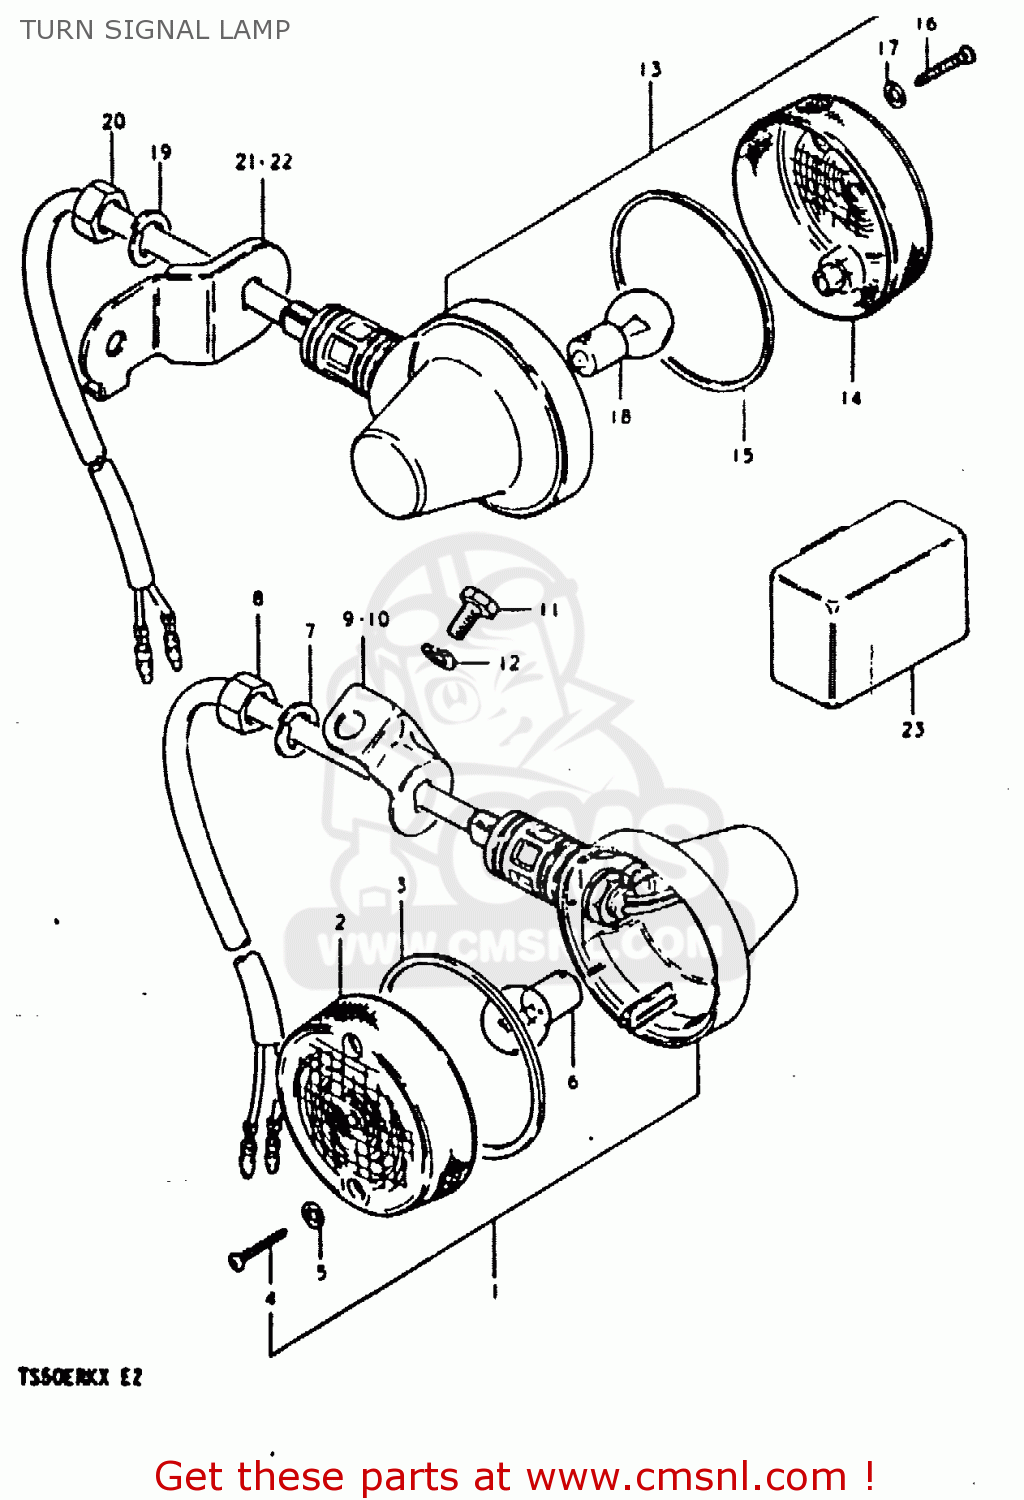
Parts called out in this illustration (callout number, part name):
1	LAMP ASSY,RR TURNSIGNAL
2	LENS
3	GASKET (NAS)
4	SCREW TAPP.
5	GASKET (NAS)
6	BULB (6V,18W)
7	WASHER,LOCK 12
8	NUT
9	BRACKET,TURNSIGNAL LAMP,R
10	BRACKET,TURNSIGNAL LAMP,L
11	BOLT
12	LOCK WASHER
13	LAMP ASSY,RR TURNSIGNAL
14	LENS
15	GASKET (NAS)
16	SCREW TAPP.
17	GASKET (NAS)
18	BULB (6V,18W)
19	WASHER,LOCK 12
20	NUT
21	BRACKET,REAR TURN SIGNAL
22	BRACKET,REAR TURN SIGNAL
23	RELAY,TURN SIGNAL
